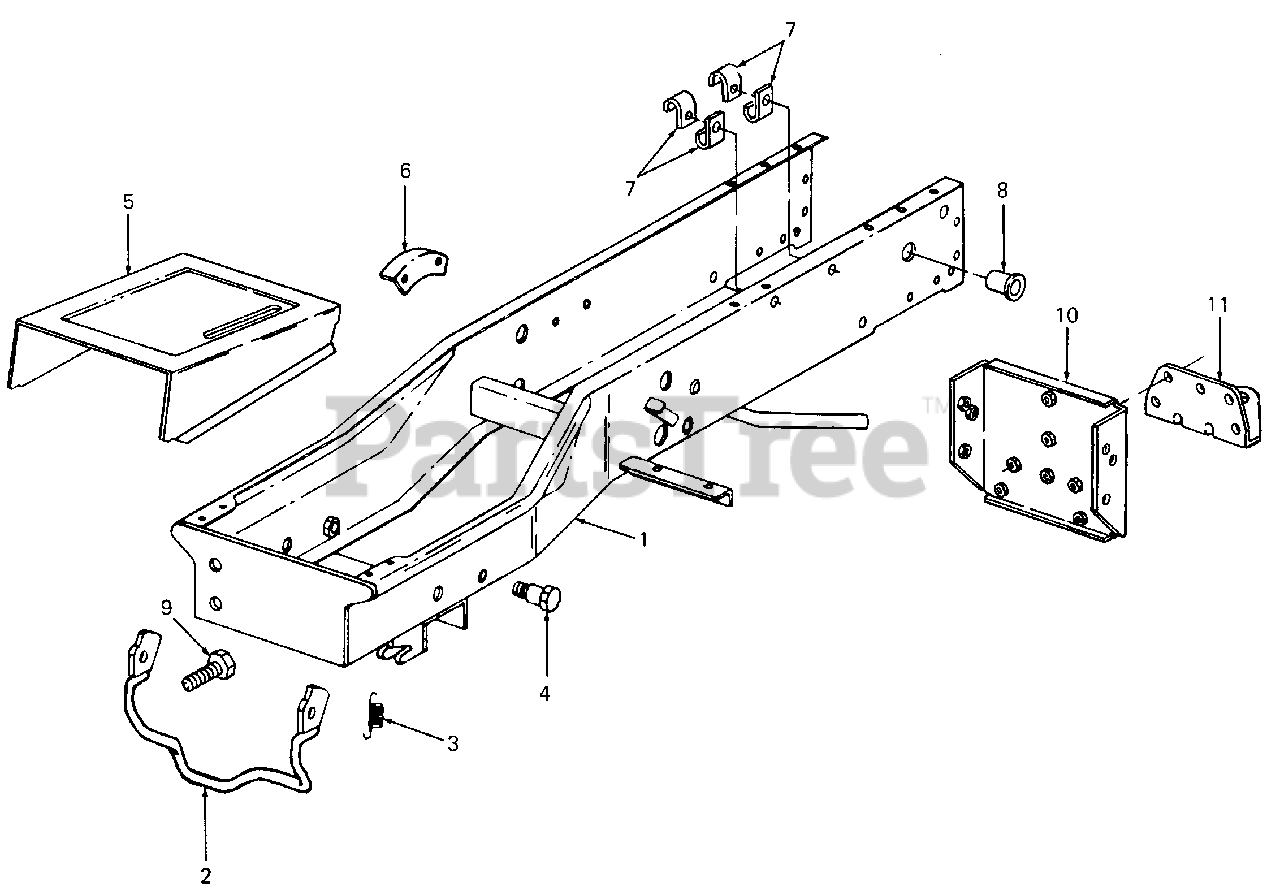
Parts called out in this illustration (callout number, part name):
1	Frame Assy
3	Spring, Latch
4	Bolt, Shoulder
5	Cover, Frame w/Graphic
6	Bracket, Height Indicator
7	Clip, Cable
8	Bushing, Snap
9	Screw, Adjustment, 1/2-20 X 1.0 Lg GR5
10	Plate Assy, Hitch
